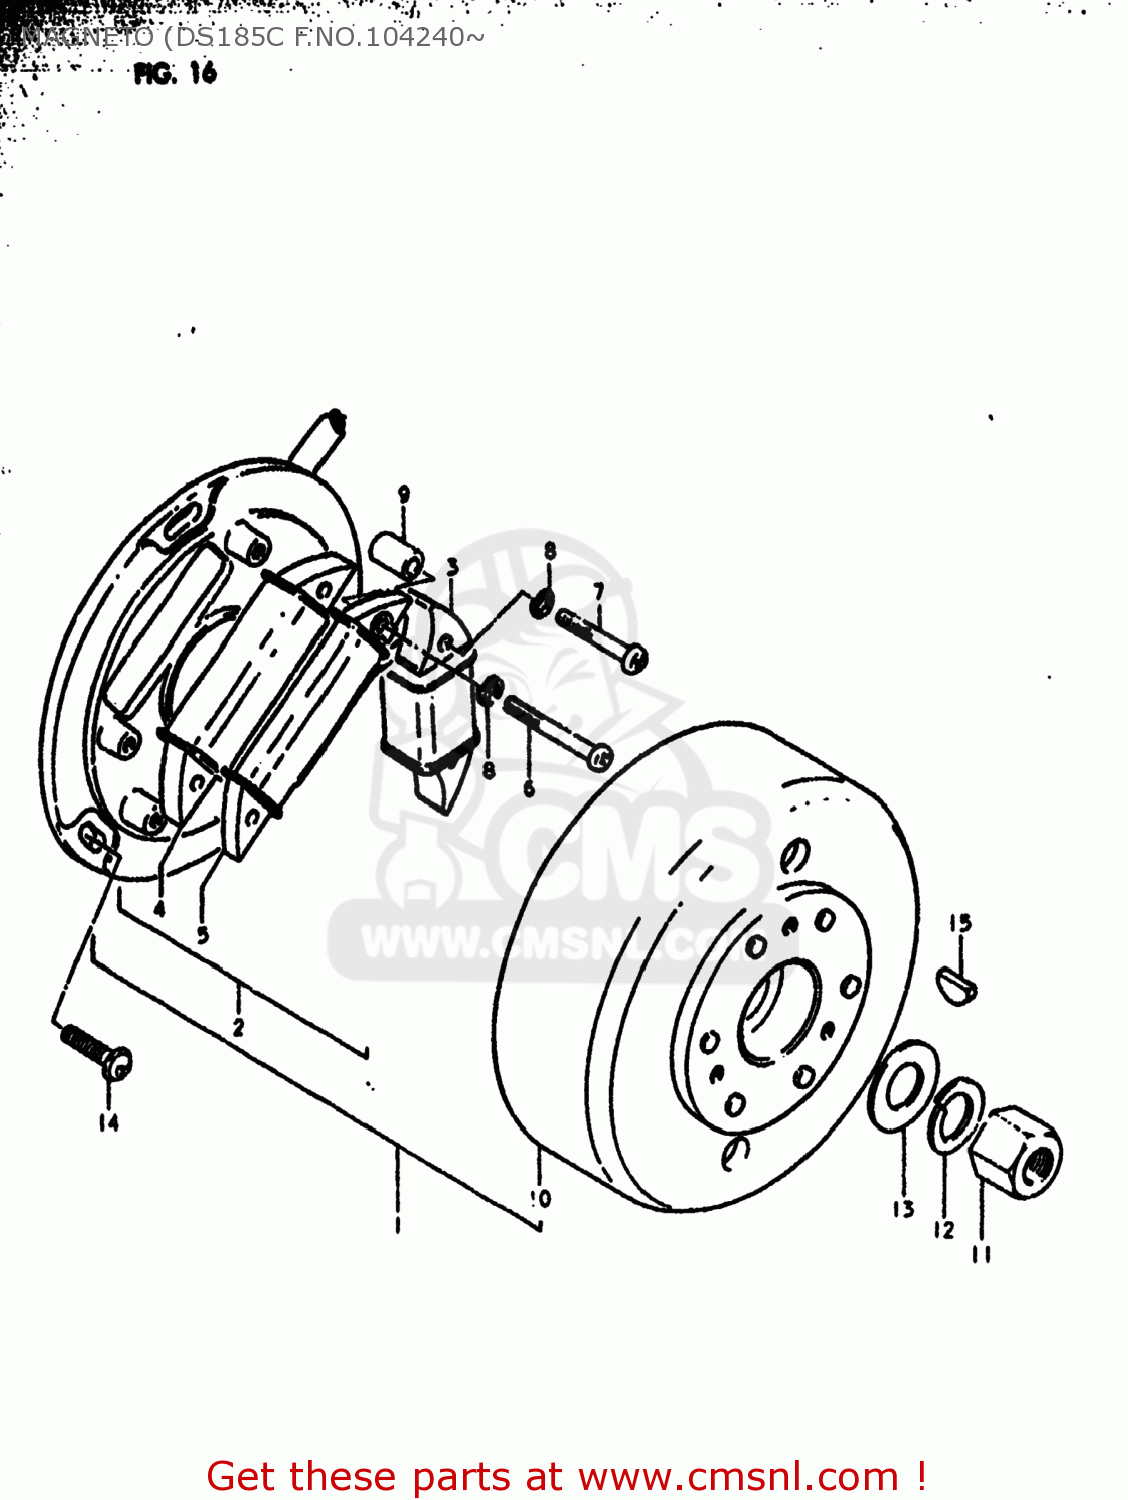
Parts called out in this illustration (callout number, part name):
1	MAGNETO ASSEMBLY
2	STATOR ASSEMBLY
3	COIL,LIGHTING
4	COIL
5	COIL,PULSER
6	SCREW
7	SCREW
8	LOCK WASHER
9	COIL ASSEMBLY,PICK-UP
10	ROTOR ASSEMBLY
11	NUT
12	LOCK WASHER
13	WASHER(14X27X3)
14	SCREW(5X14)
15	KEY 4MM
